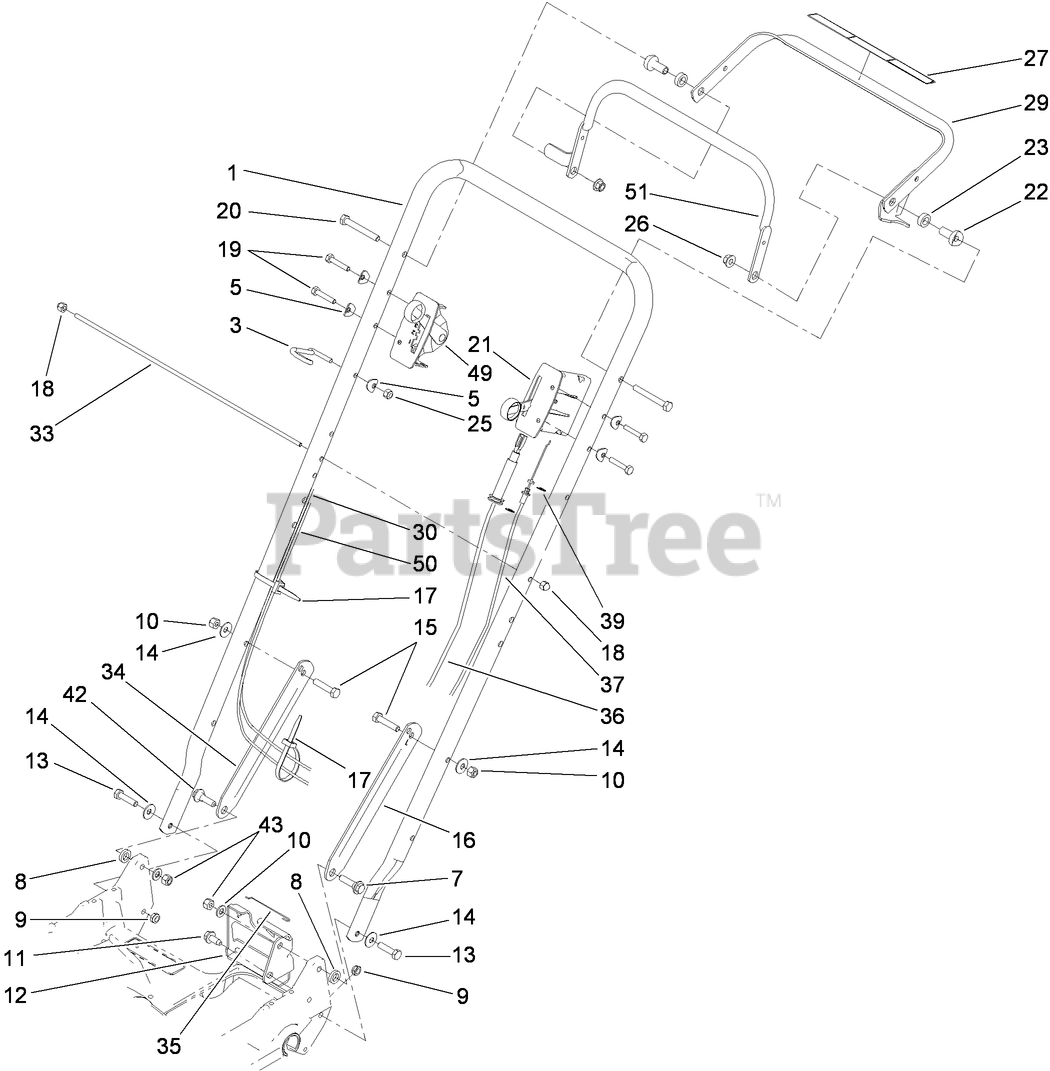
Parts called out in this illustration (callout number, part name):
1	HANDLE-PROLINE
3	GUIDE-ROPE
5	WASHER
7	SCREW-SHOULDER
8	SPACER
9	NUT-LOCK, NI
10	NUT-LOCK, NI
11	SCREW-HWHTF
12	BRACKET-ADJUSTMENT, TRACTION
13	SCREW-HH
14	WASHER-BELLEVILLE
15	SCREW-HH
16	LATCH-HANDLE, LH
17	TIE-CABLE
18	NUT-CAP
19	SCREW-HH
20	SCREW-HH
21	CONTROL-HEAD, THROTTLE
22	SPACER-SUPPORT
23	SPACER-NYLON
25	NUT-LOCK, NI
26	NUT-LOCK, NI
27	DECAL-OPERATION
29	TRACTION BAIL ASM
30	CABLE-BRAKE
33	ROD-SUPPORT, BAG
34	LATCH-HANDLE, RH
35	RETAINER-CABLE
36	CABLE-TRACTION
37	THROTTLE CABLE ASM
39	E-RING
42	SCREW-SHOULDER
43	WASHER-PLAIN
49	CONTROL-SHIFT
50	CABLE-SHIFT
51	BRAKE BAIL ASM
